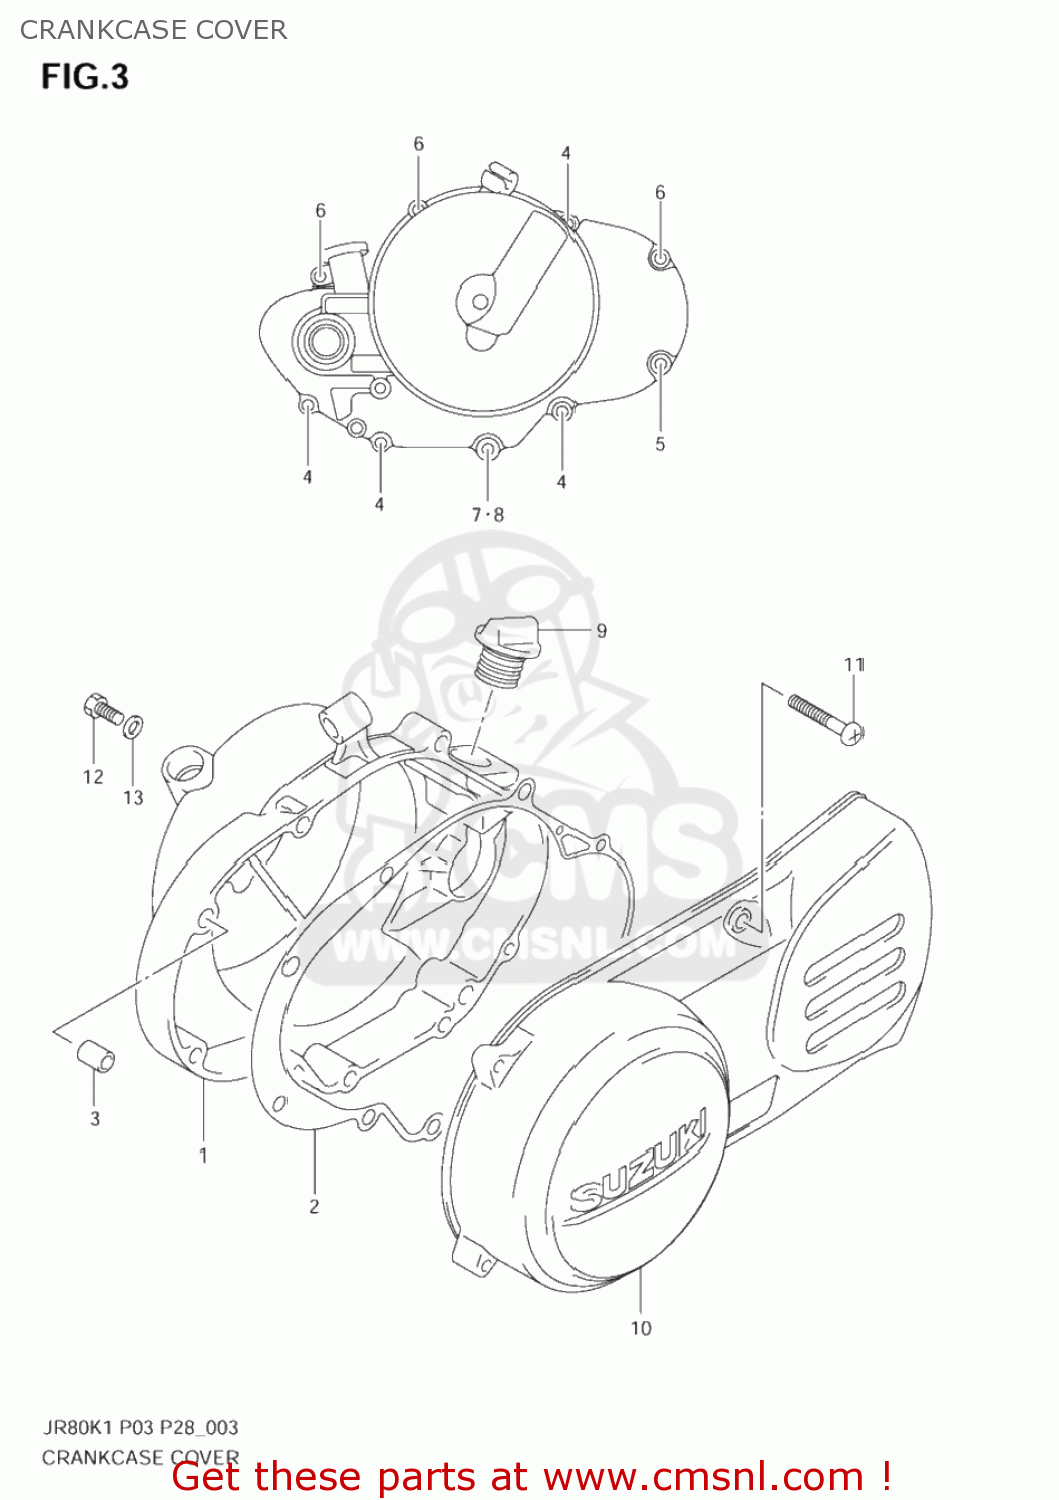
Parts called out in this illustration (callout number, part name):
1	COVER,CLUTCH
2	GASKET,CLUTCH COVER (NAS)
3	PIN
4	SCREW
5	SCREW 6X30
6	SCREW
7	SCREW
8	GASKET(6.2X11X1).2 (NAS)
9	PLUG
10	COVER,MAGNETO
11	SCREW
12	SCREW(6X10)
13	GASKET(5.8X13X1.2) (NAS)
